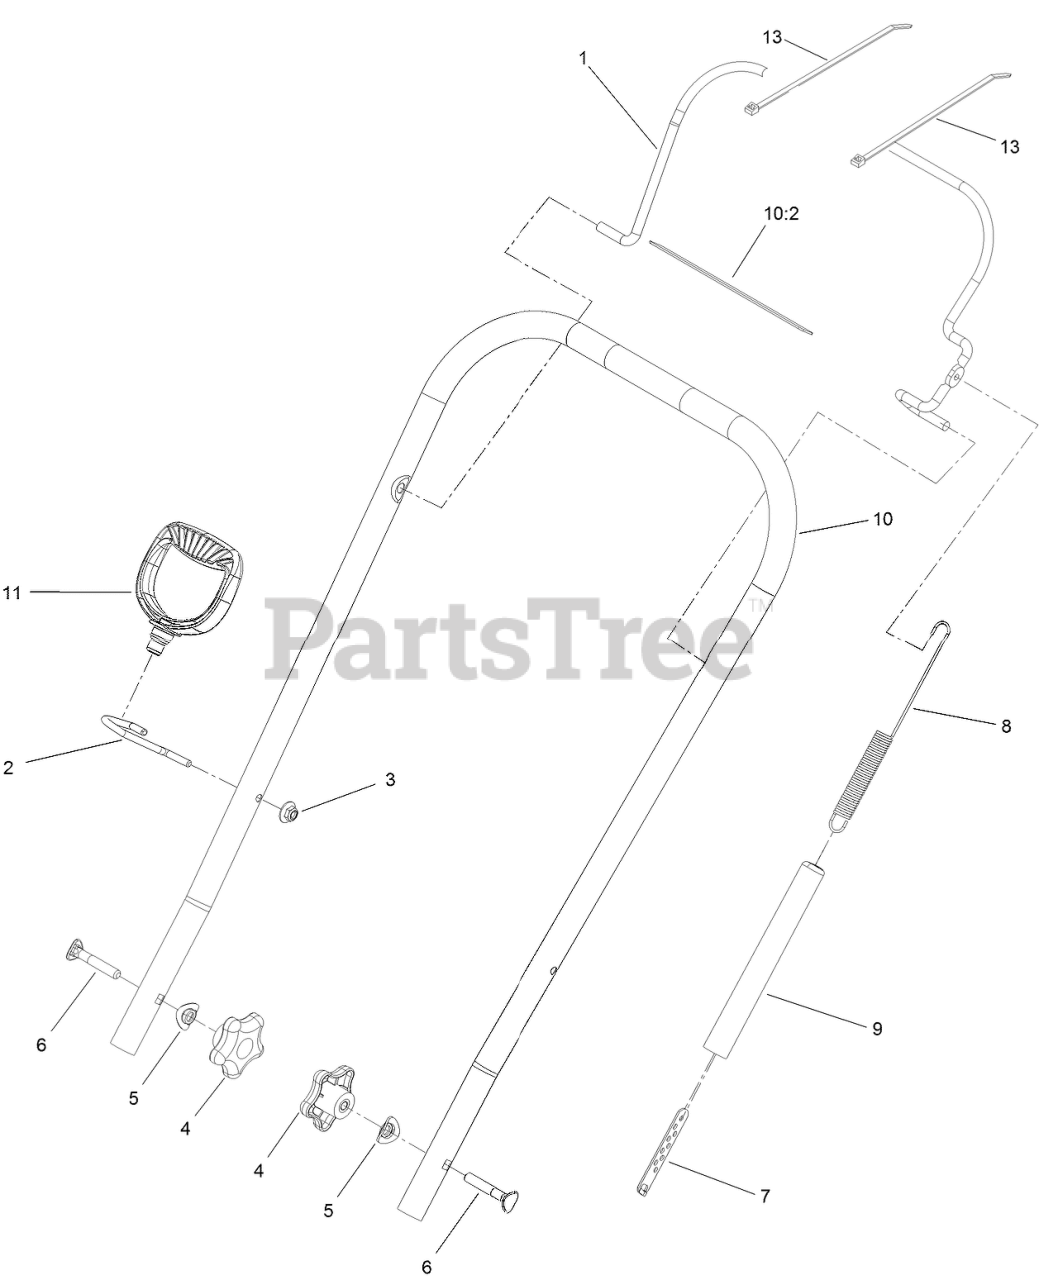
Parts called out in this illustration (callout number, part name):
1	BAIL-CLUTCH
2	GUIDE-ROPE
3	NUT-HEX FLG
4	KNOB-HANDLE
5	WASHER
6	SCREW-HANDLE
7	ADJUSTER-CABLE, CLUTCH
8	SPRING-CLUTCH
9	COVER-SPRING
10	UPPER HANDLE ASM
10:2	DECAL-SAFETY
11	HANDLE-RECOIL
13	TIE-CABLE
